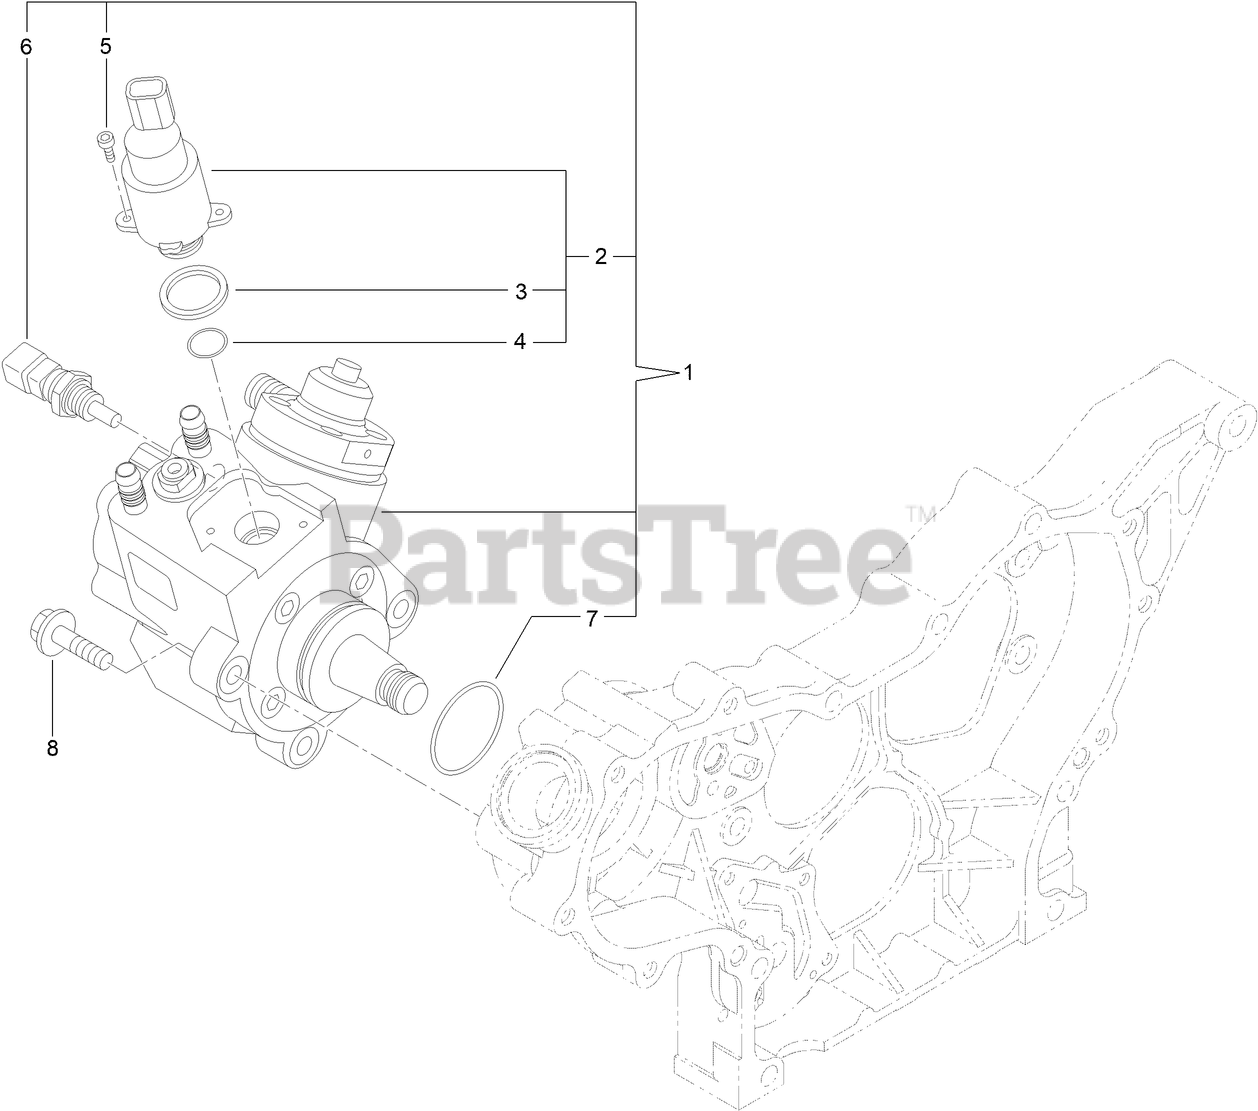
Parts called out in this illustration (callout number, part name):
1	FUEL PUMP ASM
2	VALVE ASM
3	RING-SEALING
4	O-RING
6	SENSOR-TEMPERATURE
7	O-RING
